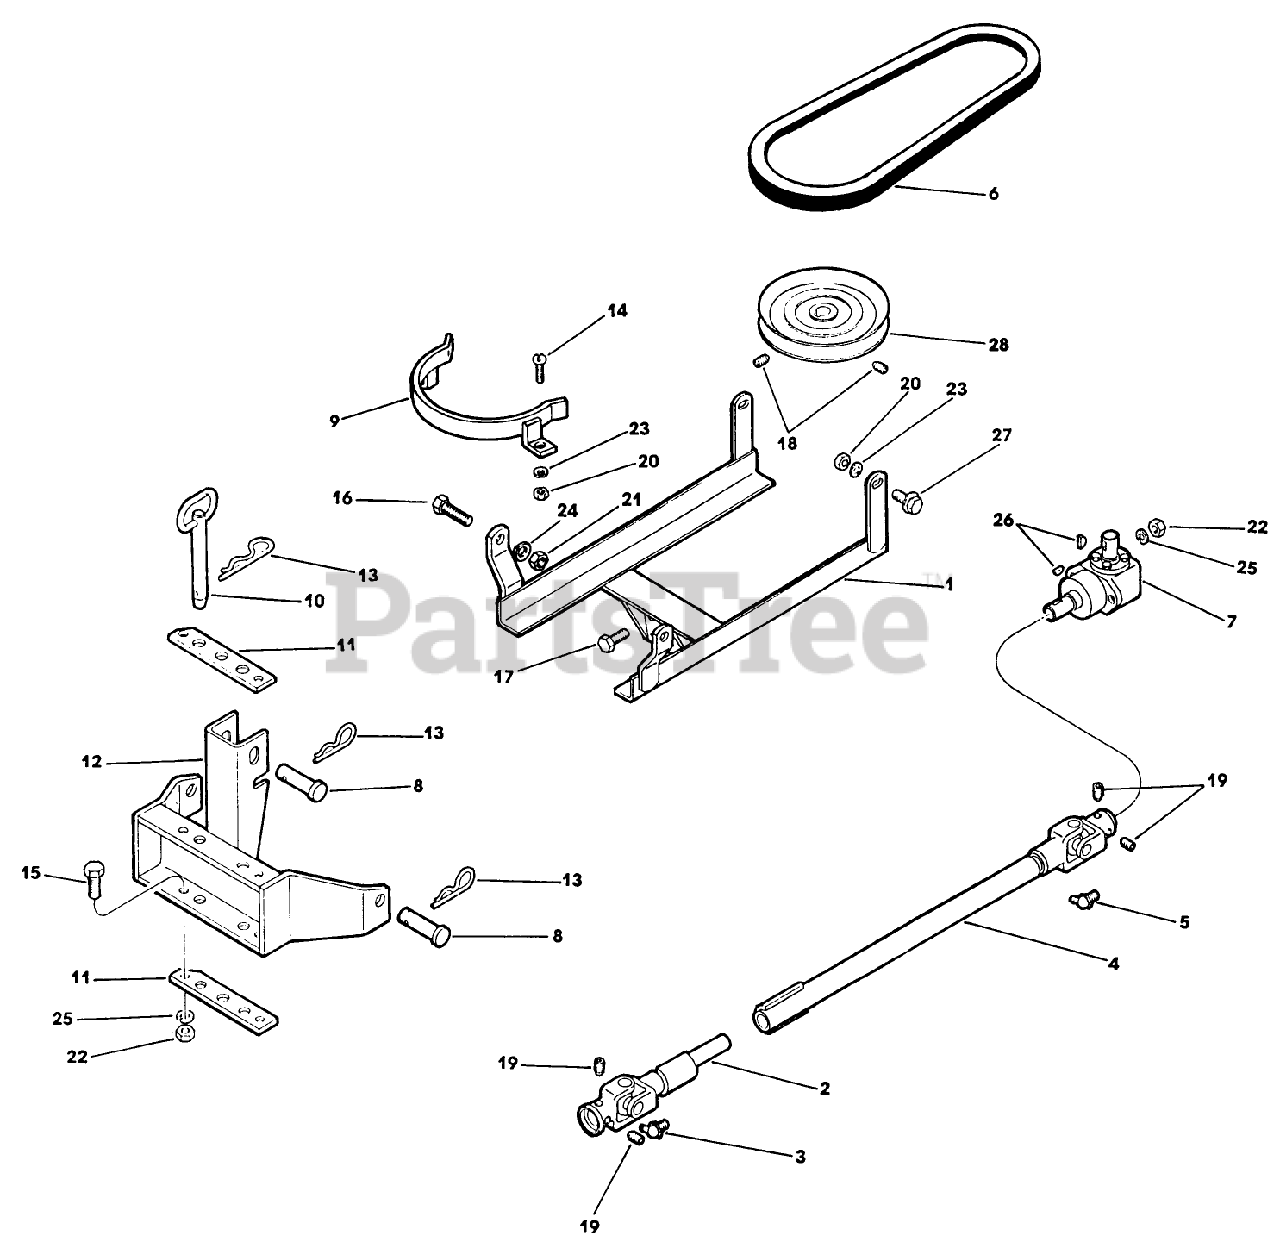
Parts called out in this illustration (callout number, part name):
2	UNI COUPLING
4	DRIVE TUBE AY *B
7	GEAR BOX
10	PIN AY. - HITCH
18	SET SCREW
